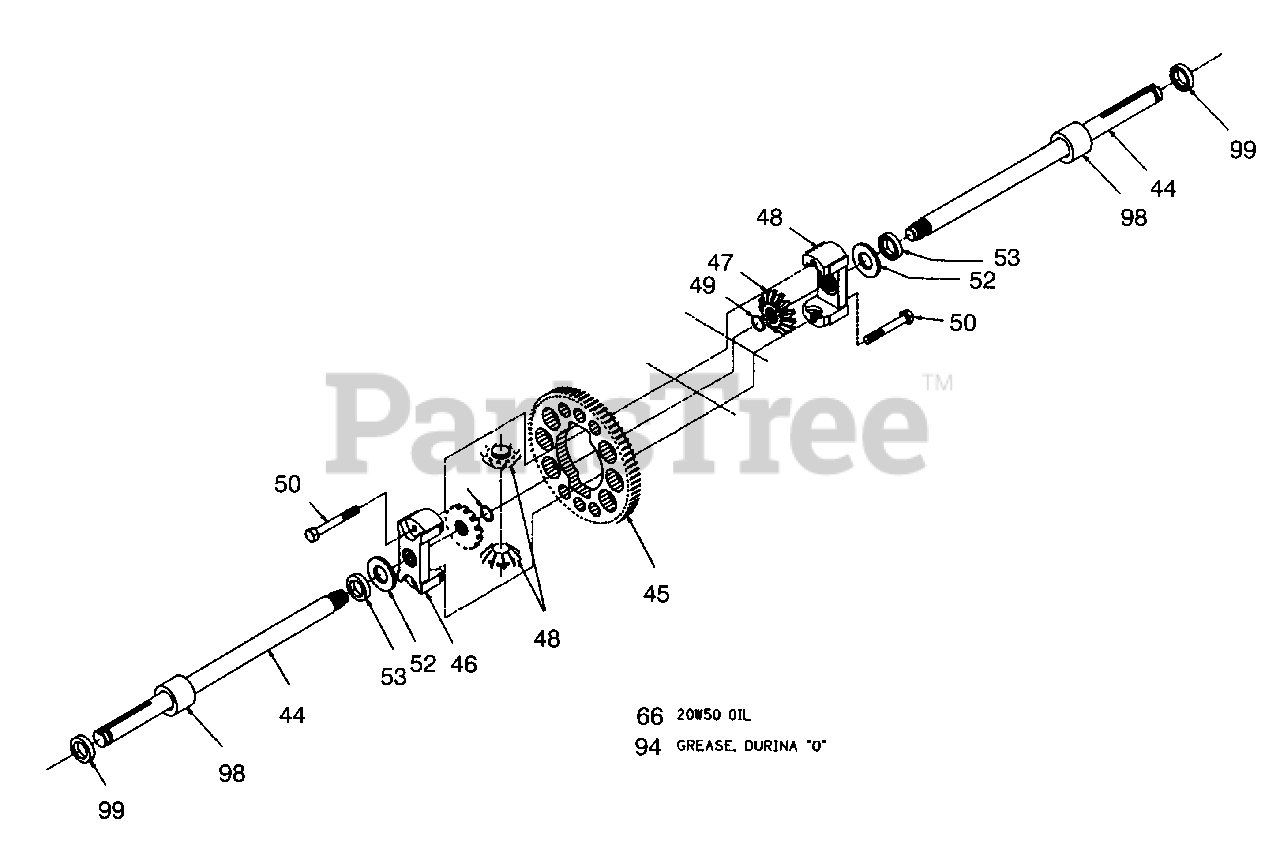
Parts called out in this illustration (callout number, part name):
26	Plate-Bypass
44	Shaft-Axle
46	Housing-Diff.
49	Ring-Retaining
50	Bolt-Diff. Locking
52	Washer
53	Seal
94	Grease Durina "O"
98	Sleeve-Bearing
99	Seal-Wiper
